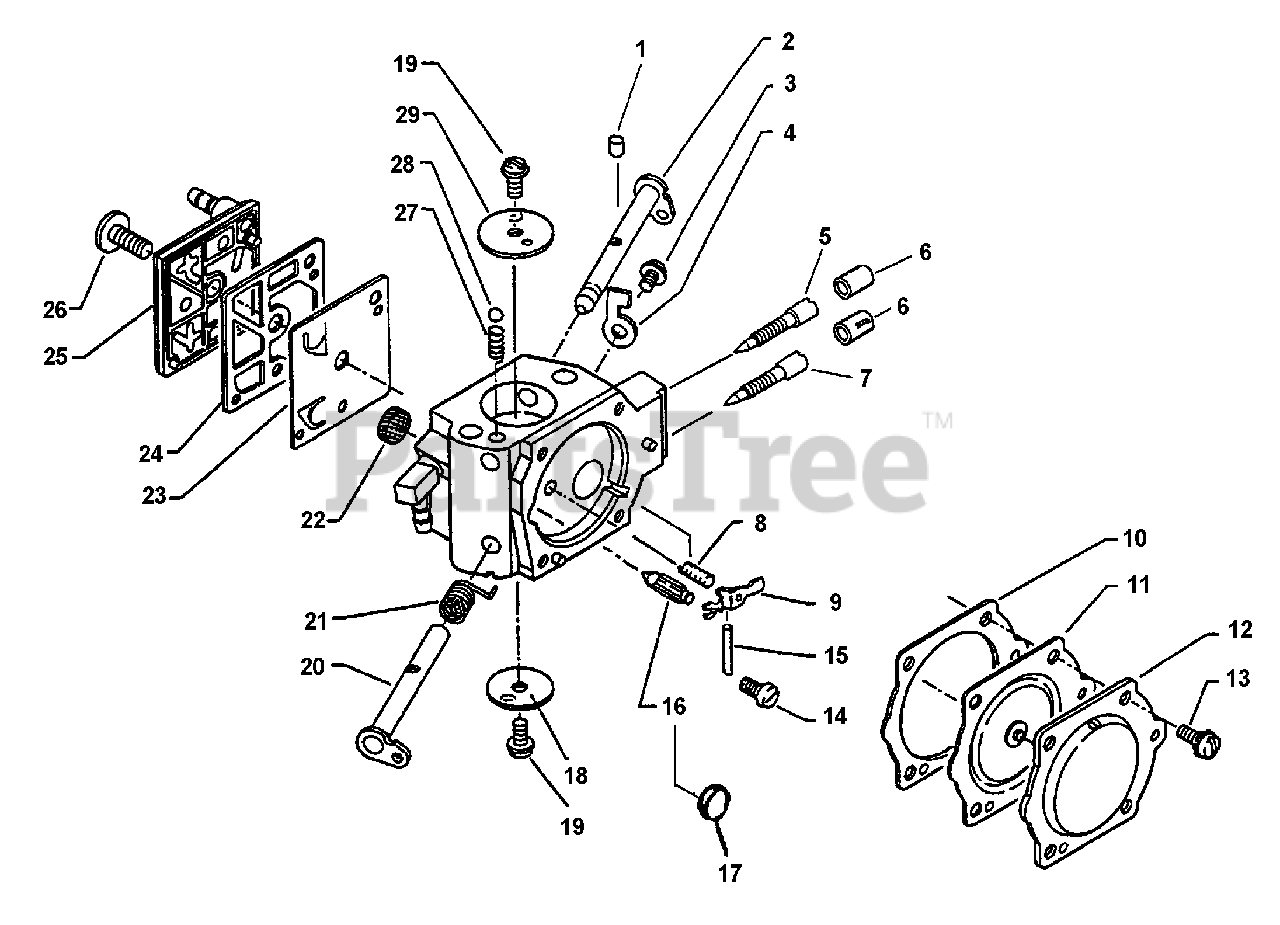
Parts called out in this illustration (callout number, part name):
1	PLUG, FRICTION
2	SHAFT, CHOKE
4	STOP, THROTTLE
5	NEEDLE, HIGH SPEED
6	CAP, LIMITER
7	NEEDLE, LOW SPEED
8	SPRING, METERING LEVER
9	LEVER, METERING
10	GASKET, METERING
11	DIAPHRAGM, METERING
12	COVER, METERING DIAPHRAGM
13	SCREW
14	SCREW, METERING LEVER PIN
15	PIN, METERING LEVER
16	VALVE, INLET NEEDLE
17	PLUG, WELCH
18	VALVE, THROTTLE
20	SHAFT, THROTTLE
21	SPRING, THROTTLE RETURN
22	STRAINER
23	DIAPHRAGM, PUMP
24	GASKET, PUMP
25	COVER, FUEL PUMP
28	BALL, CHOKE FRICTION
29	VALVE, CHOKE
